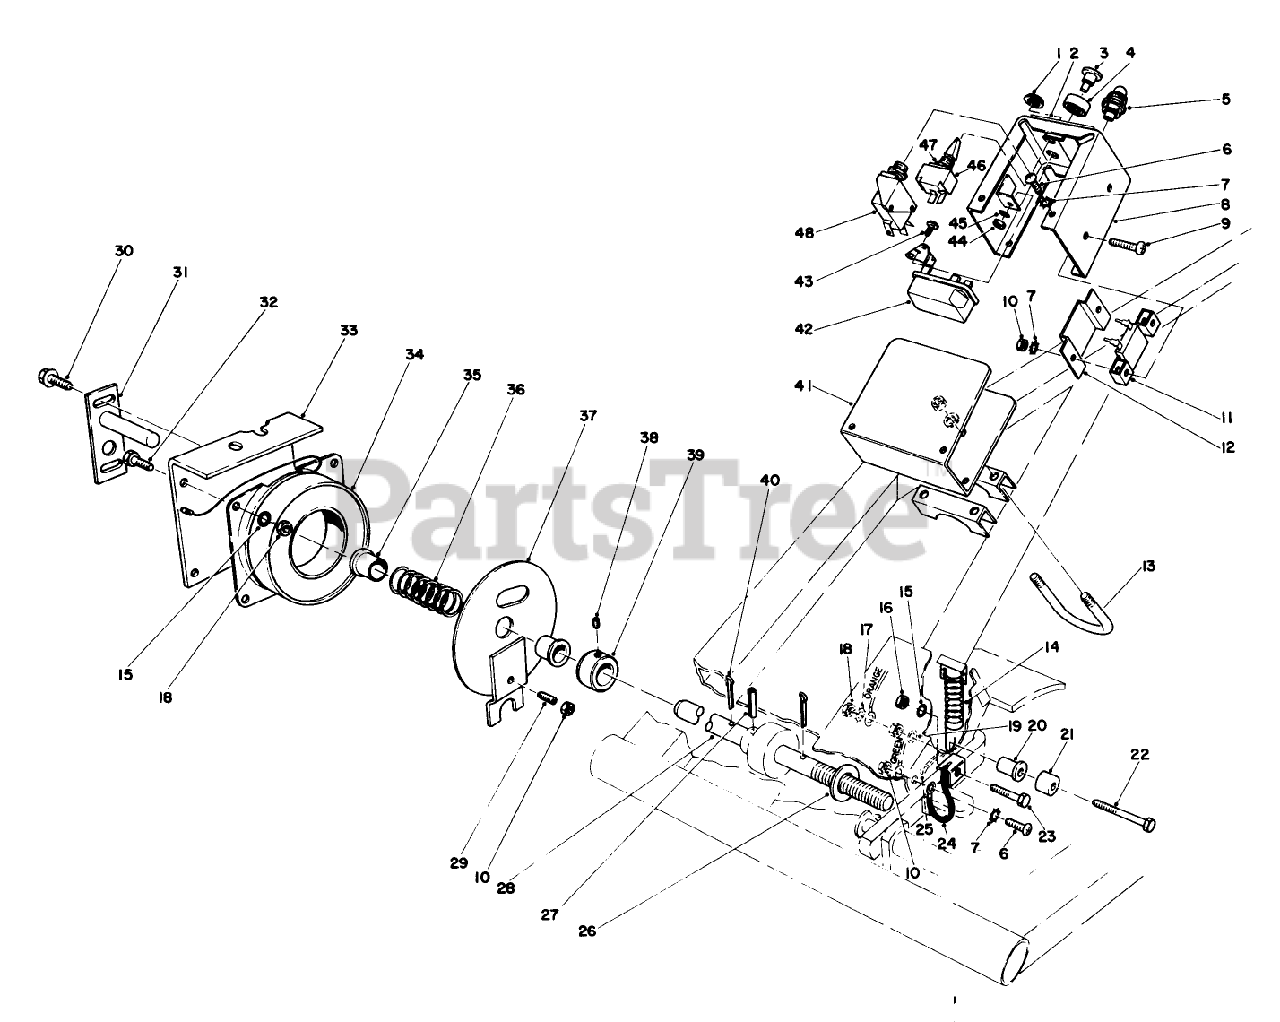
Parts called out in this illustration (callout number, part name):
1	NUT-BULB
2	SPEED CONTROL DECAL
3	BUTTON-PUSH
4	BEZEL
5	Light-Warning
6	SCREW-PPH
7	WASHER-LOCK/EXT
8	Box Cover
9	SCREW-HH
10	NUT-HEX
11	Resistor
12	RESISTOR GUARD
13	MUFFLER CLAMP
14	Extension Spring Assembly
15	WASHER-LOCK
16	NUT-JAM
17	WASHER-LOCK/EXT
18	NUT-HEX
19	WASHER-FLAT
20	NUT-INSERT
21	CONTACT SPACER
22	SCREW-HH
23	SCREW-HH
24	Grounding Clip Assy (w/wire)
25	PIN-COTTER
26	SPACER
27	PIN-SPRING
28	TRACTION PEDAL SHAFT
29	SCREW-HSH
30	SCREW-HHF
31	Shaft
32	SCREW-HH
33	BRACKET R
34	CORE-FIELD, COIL
35	BUSHING-FLANGE
36	SPRING-COMPRESSION
37	Clutch Plate
38	Socket Hd. Set Screw
39	Collar (Incl. Ref. #38)
40	PIN-COTTER
41	BOX WA B
42	Relay Switch
43	6 32 3/8 RD HD MS
44	NUT-HEX
45	WASHER-LOCK, INTERNAL
46	Light Switch (Incl. Ref. #1 & 47)
47	NUT-LOCK
48	Switch
